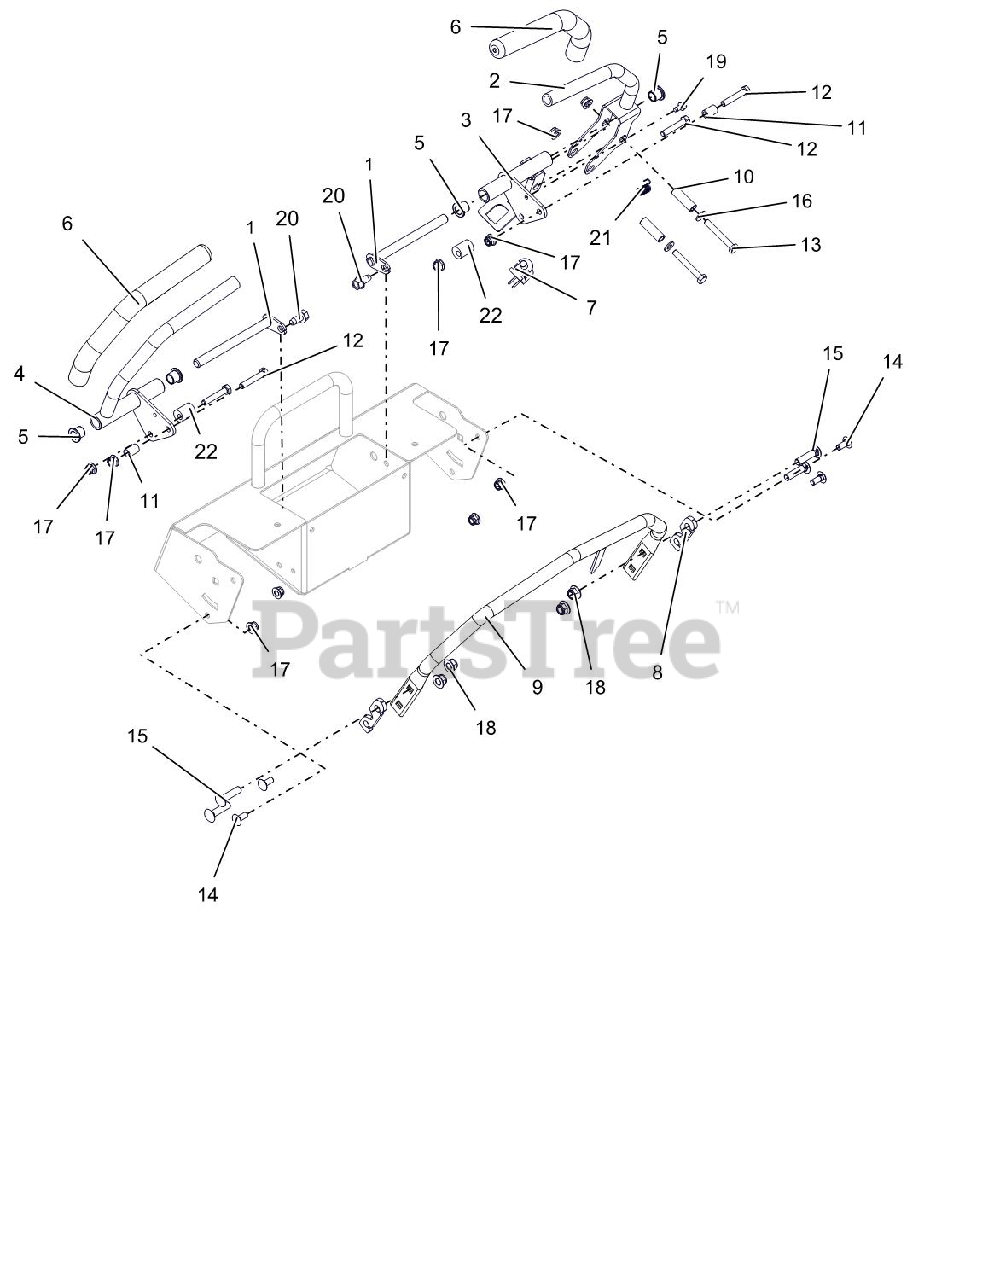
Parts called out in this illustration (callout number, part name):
1	WLDT, PIN AND LOCK Y
2	WMT, CONTROL ARM OPC
3	WMT, CONTROL ARM (LH)
4	WMT, CONTROL ARM (RH)
5	BRG, FLG .500X.620X.500 BRNZ
6	GRIP, HANDLEBAR
7	SWITCH- SNAP MTG N.O.
8	SHIM, 5 DEG SPEED BAR
9	BAR, FORWARD STOP PRO-STANCE
10	BSHG-SLV .325X.49X1.56
11	BSHG-SLV .328X.50X.75
12	@BLT-HEX .31-18X1.75 GR5 YWZC
13	@BLT-HEX .31-18X2.25 GR5 YWZC
14	@BLT-RDHDSQNK .31-18X.75 G5YZ
15	@BLT-RDHDSQNK .38-16X1.50 G5YZ
16	@WSHR-FL-STL.344X.688X.065YWZC
17	@NUT-LK-NYL-FLG .31-18 YWZC
18	@NUT-LK-NYL-FLG .38-16 YWZC
19	SCR-TAP .25-20X.50 HWH TR YWZ
20	@SCR-TAP .38-16X.75 HWH TR YWZ
21	SPRING, EXT. .043X.438X1.64
22	ECCENTRIC
